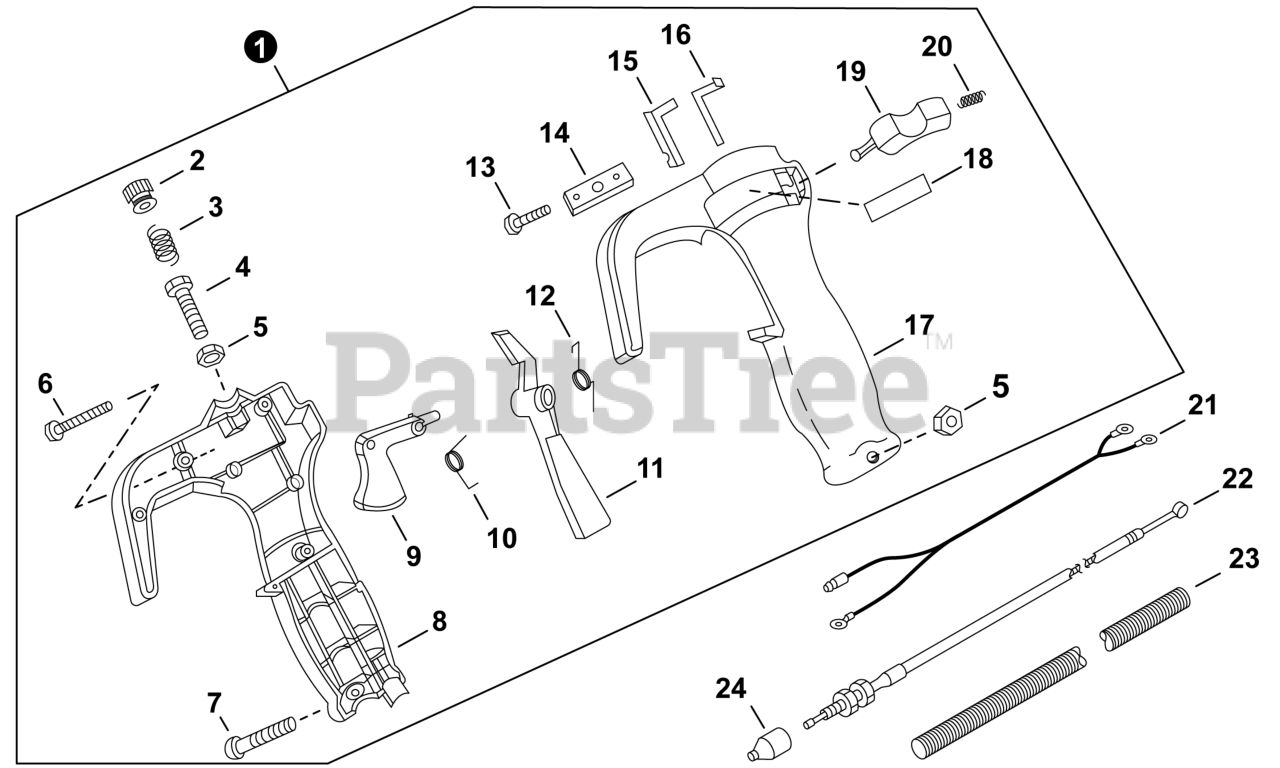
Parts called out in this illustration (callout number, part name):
1	THROTTLE CONTROL ASSY
8	GRIP, RIGHT
9	TRIGGER, THROTTLE
11	LOCKOUT, THROTTLE
17	GRIP, LEFT
18	LABEL - STOP-START
19	SWITCH, START-STOP
22	CABLE, THROTTLE
23	TUBE, FLEXIBLE
24	CAP, DUST
